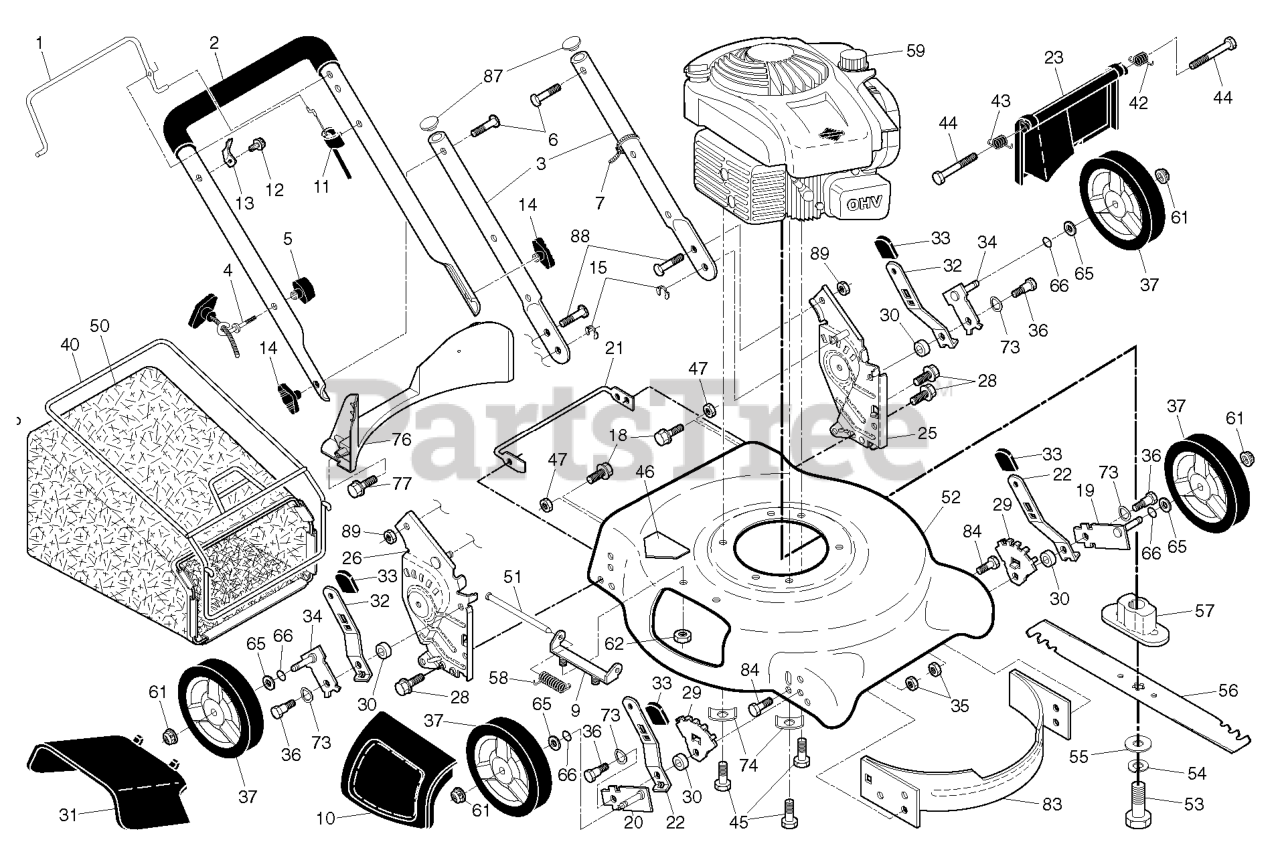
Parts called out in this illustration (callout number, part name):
1	CONTROL BAR
2	HANDLE.UP.ASM.DST.ECON.498.GRP
3	HANDLE.LOWER.DOME.BT.GREY
4	GUIDE.ROPE.BLK.ZINC.CHROM
5	T-KNOB.NEW ROPE GUIDE
6	BOLT, HANDLE 5/16-18X1.75
7	TIE GUIDE
9	BRACKET.ASM.HOUSING.EZ.MUL
10	DOOR.MULCH.21".REAR.PUSH.GRAY
11	CABLE.MZR.22.2012
13	BRACKET.UPSTOP.RT
14	KNOB, DEFLECTOR
18	SCREW 1/4X20
19	AXLE ARM ASSY FRONT LH
20	AXLE ARM ASSY FRONT RH
21	FOOT.GUARD.21.DOM/FGD.CE.10
22	SELECTOR SPRING, FRONT
23	DOOR.REAR.21.DOMED.498
25	BRACKET.ASM.HAND.LW.21.LT.GREY
26	BRACKET.ASM.HAND.LW.21.RT.GREY
28	SCREW 14-20 X 5/8
29	WHEEL ADJ BRACKET FRONT
30	SPACER.HEIGHT.ADJUSTER
31	DEFLECTOR.CLIPPING.21.GREY
32	SPRING.SELECTOR.21RD.HTTRT.BZP
34	ARM.ASM.AXLE.REAR.5/9.POS.BZP
35	NUT.FLANGE.HEX.5/16X18.BLACK
36	SHOULDER BOLT 5/16-18
37	WHEEL & TIRES ASSY, FRONT
40	FRAME.BAG.21.REAR.DOMED.PUSH
42	SPRING.LH.22.REAR.DOOR.EZ.EMPT
43	SPRING.RH.22.REAR.DOOR.EZ.
45	BOLT 3/8-16X1-1/8
46	DECAL.INTERNATIONL.CUTFINGER
47	NUT.71038.31-18.HEX.NYLOCK
50	GBAG.2323029ER.HU.VENT.GRY.SIL
51	ROD.HINGE.COMBI-C
52	HOUSING.21MC.DOME.ORANGE.CE
53	SCREW, HEX HD 3/8-24 X 1-3/8
54	LOCKWASHER
55	WASHER,HARDEN
56	BLADE.21.PUSH
57	ADAPTOR.BLADE.7/8
58	TORSION SPRING
61	NUT.HEX.FLANGE.3/8-16.LO(3 2)
62	LOCKNUT.NYLOC.1/4-20
65	WASHER.FLAT.1/2
66	O-RING..070X.487.NEOPRENE
73	WASHER.CURVED.CYLINDRICAL
74	WASHER.ENGINE.BZP
76	BAFFLE.REAR.PLASTIC.21.RD.ECON
77	SCREW.HX.13X.750
83	BAFFLE.FRONT.21.DOME.US
84	BOLT.5/16HEX.WHS.HD
87	PLUG.PLASTIC.7/8".14-20.GAUGE
88	BOLT.CARRIAGE.LN.5/16-18X.5/8
89	LOCKNUT-FLANGE 5/16-18
